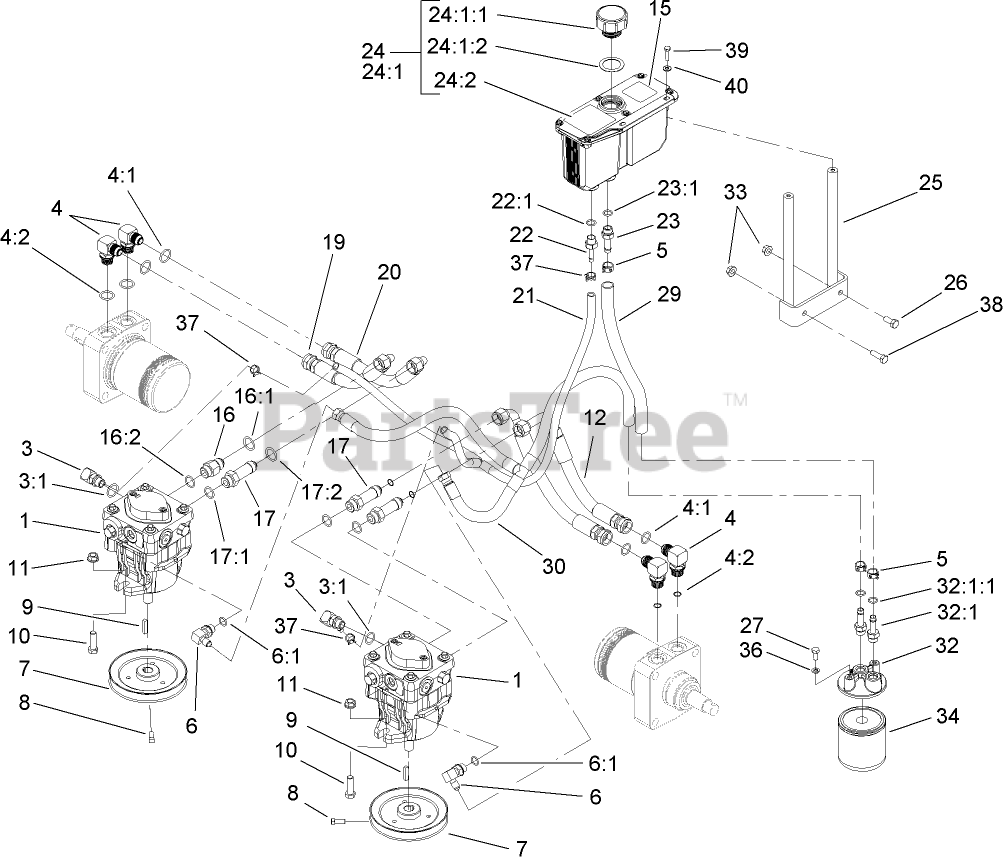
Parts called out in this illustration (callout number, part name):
1	PUMP-HYDRAULIC
3	ELBOW-90 DEG
3:1	O-RING
4	FITTING-90 DEG
4:1	O-RING
4:2	O-Ring
5	Clamp-Hose
6	FITTING-ELBOW, 90 DEG
6:1	O-Ring
7	PULLEY
8	SCREW-SET
10	SCREW-HH
11	NUT-HHF, WHIZ
12	HOSE-REAR, LH
15	DECAL-EXHAUST
16	ADAPTER-STRAIGHT
16:1	O-RING
16:2	O-Ring
17	ADAPTER-HYD, STRAIGHT
17:1	O-RING
17:2	O-Ring
19	HOSE-REAR, RH
20	HOSE-REAR, RH
21	HYD HOSE ASM
22	Adapter-Straight
22:1	O-RING
23	ADAPTER-STRAIGHT
23:1	O-RING
24	HYD Reservoir ASM
24:1	Reservoir-HYD
24:1:1	CAP-RESERVOIR, HYD
24:1:2	GASKET-CAP
24:2	DECAL-TANK, HYD
25	STAND-RESERVOIR
26	SCREW-HH
27	SCREW-HH
29	HYD HOSE ASM
30	HYD HOSE ASM
32	Filter Head ASM
32:1	ADAPTER-STRAIGHT
32:1:1	O-RING
33	NUT-HF
34	FILTER-OIL, HYD (WINTER)
34	FILTER-OIL, HYD
36	WASHER-LOCK
37	Clamp-Hose
38	SCREW-HH
39	SCREW-HH
40	WASHER-FLAT
